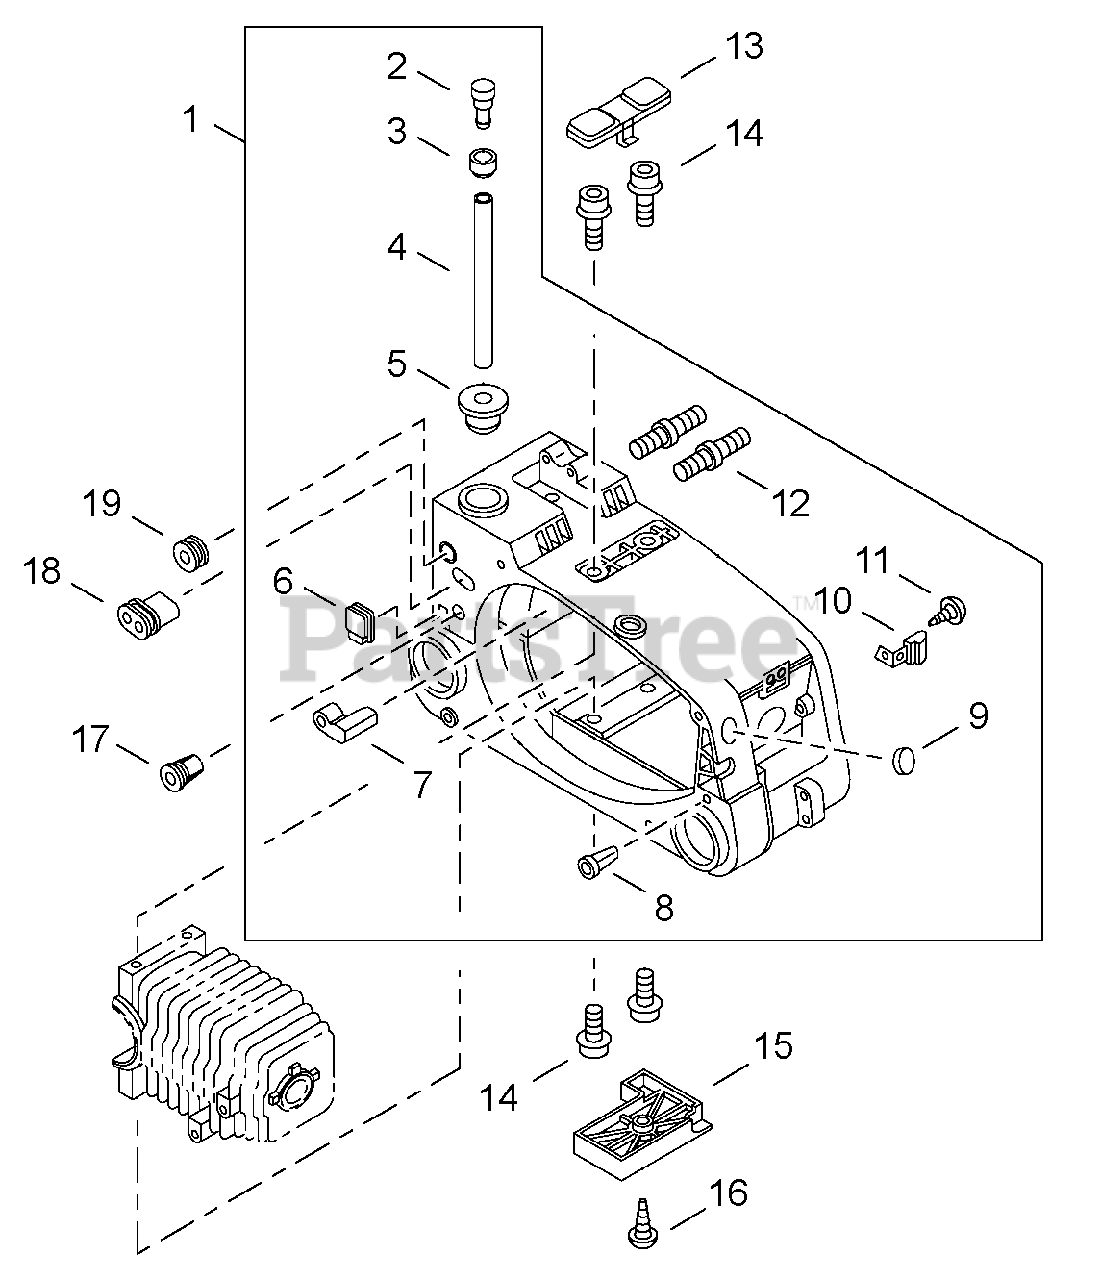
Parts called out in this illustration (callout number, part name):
1	ENGINE COVER KIT
2	VENT, FUEL TANK
3	HOLDER, VENT
4	PIPE - 3X5X150 -- BLACK
5	GROMMET
8	VENT, TANK
11	SCREW - 4X10
12	STUD, GUIDE BAR
13	COVER - ORANGE
14	SCREW - 5X16
15	COVER, BOTTOM - ORANGE
16	SCREW - 4X16
